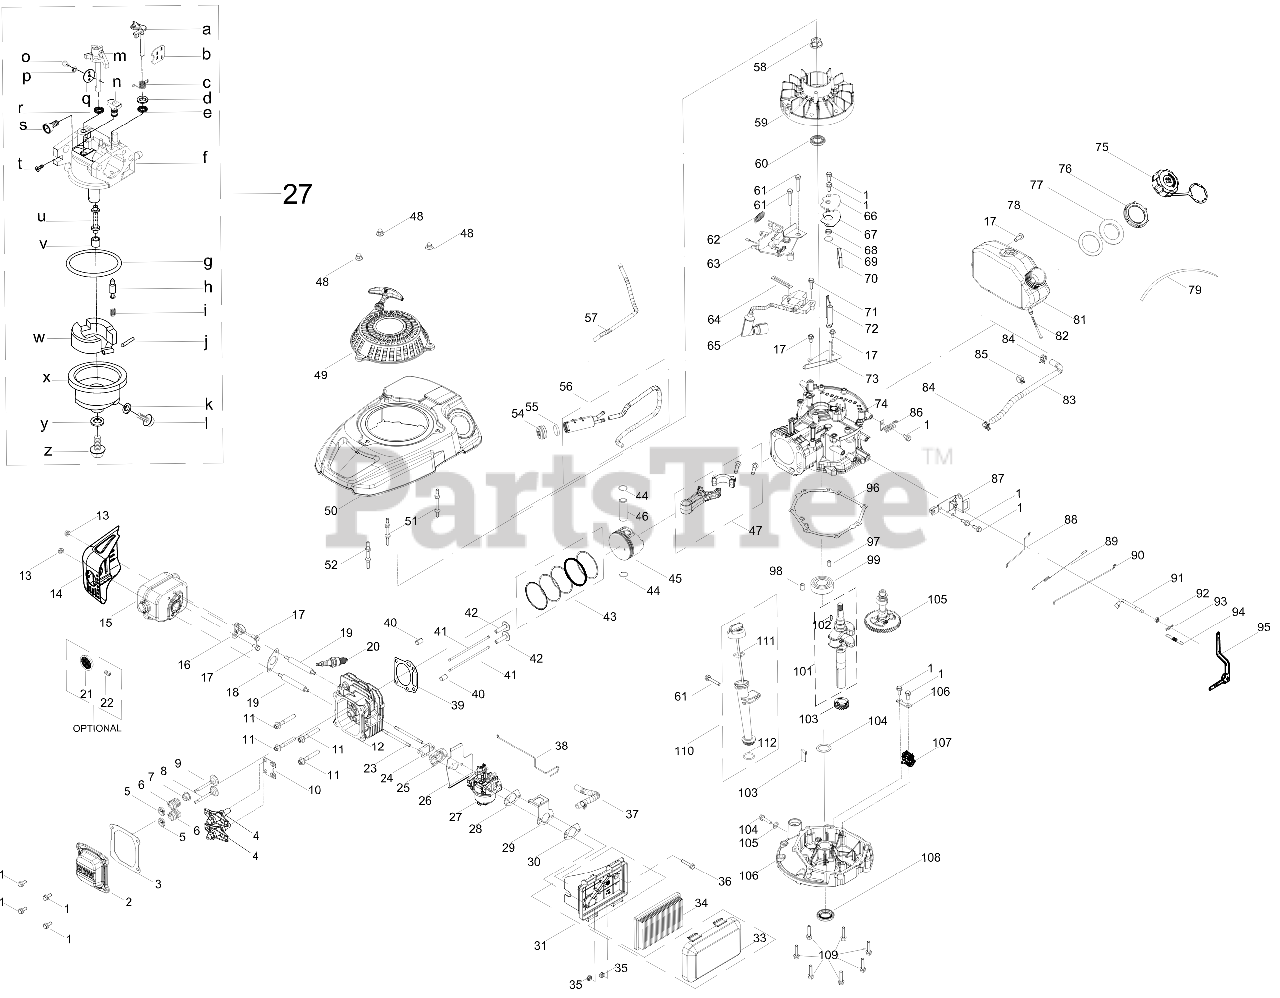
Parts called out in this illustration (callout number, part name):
1	BOLT M6-1 x 14 GR8.8
2	VALVE COVER
3	VALVE COVER GASKET
4	ROCKER ARM ASSEMBLY
5	VALVE SPRING RETAINER
6	VALVE SPRING
7	INTAKE VALVE SEAL
8	EXHAUST VALVE
9	INTAKE VALVE
10	PUSH ROD GUIDE
11	BOLT-M8 x 54
12	CYLINDER HEAD
14	MUFFLER SHIELD
15	MUFFLER ASSEMBLY
16	THERMOSTAT
17	BOLT M6-1 x 12 GR8.8
18	MUFFLER GASKET
19	STUD M6-1 x 95
20	SPARK PLUG
21	SPARK ARRESTOR
22	SCREW M3.5 x 9.5
23	CARBURETOR STUD-M6 x 87
24	CARBURETOR INSULATOR GASKET
25	CARBURETOR INSULATOR
26	CARBURETOR GASKET
27	CARBURETOR ASSEMBLY
28	AIR FILTER BRACKET GASKET
29	CHOKE TEMP CONTROL BRACKET
30	AIR FILTER BASE GASKET
31	AIR FILTER HOUSING ASSEMBLY
33	AIR FILTER COVER
34	AIR FILTER
36	BOLT-M6-1 x 30 GR8.8
37	BREATHER HOSE
38	CHOKE TEMP CONTROL LINKAGE
39	CYLINDER HEAD GASKET
41	PUSH ROD
42	TAPPET
43	PISTON RING SET
44	SNAP RING-PISTON PIN
45	PISTON
46	PISTON PIN
47	CONNECTING ROD ASSEMBLY
48	ACORN NUT
49	RECOIL STARTER ASSEMBLY
50	ENGINE SHROUD
51	STARTER/SHROUD REAR STUD
52	STARTER/SHROUD FRONT STUD
54	CARBON CANISTER FILTER CAP
55	CARBON CANISTER FILTER
56	CARBON CANISTER
57	CARBON CANISTER PURGE HOSE
58	FLYWHEEL NUT
59	FLYWHEEL
60	CRANKSHAFT SEAL
61	BOLT M6-1 x 35 GR8.8
62	ENGINE BRAKE SPRING
63	ENGINE BRAKE ASSEMBLY
64	FLEXIBLE CLAMP
65	IGNITION COIL
66	BREATHER COVER PLATE
67	BREATHER GASKET
68	BREATHER VALVE SPRING
69	BREATHER VALVE
70	BREATHER SCREEN
71	BOLT M6-1 x 20 GR8.8
72	AIR VANE
73	AIR VANE BRACKET
74	CRANKCASE
75	FUEL CAP ASSEMBLY
76	FUEL TANK NUT
77	FUEL TANK UPPER GROMMET
78	FUEL TANK LOWER GROMMET
79	CABLE TIE - 3 x 150
82	FUEL FILTER
84	HOSE CLAMP
85	FUEL LINE SUPPORT CLAMP
86	FLEXIBLE CLAMP
87	COMPONENT BRACKET
88	CHOKE LINKAGE
89	THROTTLE LINKAGE SPRING
90	THROTTLE LINKAGE
91	GOVERNOR ARM SHAFT
92	GOVERNOR SEAL
93	COTTER PIN
94	GOVERNOR SPRING
95	GOVERNOR ARM ASSEMBLY
96	CRANKCASE COVER GASKET
97	DOWEL PIN
98	DOWEL PIN
101	CRANKSHAFT
102	FLYWHEEL KEY
103	CRANKSHAFT TIMING GEAR
104	THRUST WASHER
105	CAMSHAFT ASSEMBLY
106	GOVERNOR GEAR MOUNTING PLATE
107	GOVERNOR GEAR/SHAFT ASSEMBLY
108	LOWER CRANKSHAFT SEAL
109	BOLT-M6-1 x 28 GR8.8
110	OIL DIPSTICK ASSEMBLY
111	O-RING
113	OIL RETURN SEAL
114	OIL DRAIN PLUG
115	WASHER
116	CRANKCASE COVER
Z	BOLT M8-1 x 10
